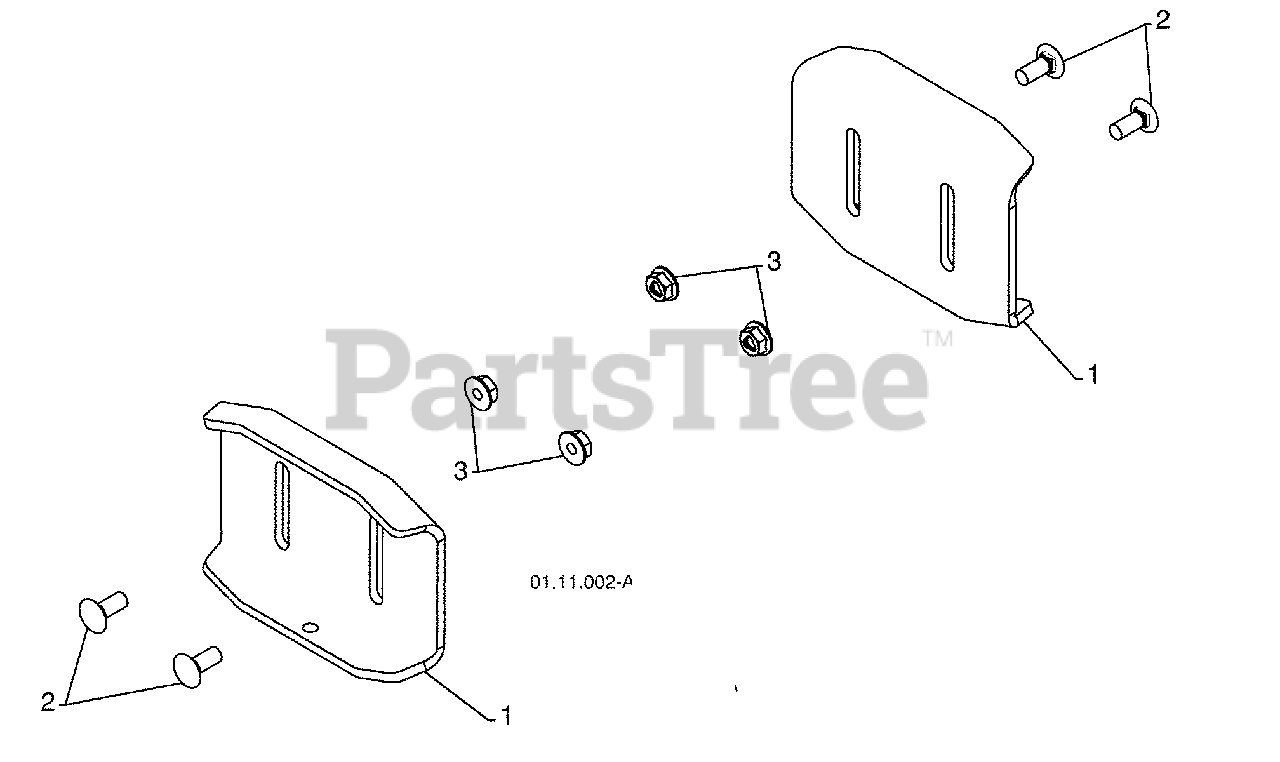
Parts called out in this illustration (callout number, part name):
1	SKID PLATE
2	CARRIAGE BOLT 5/16-18 X .750
3	NUT 5/16-18
